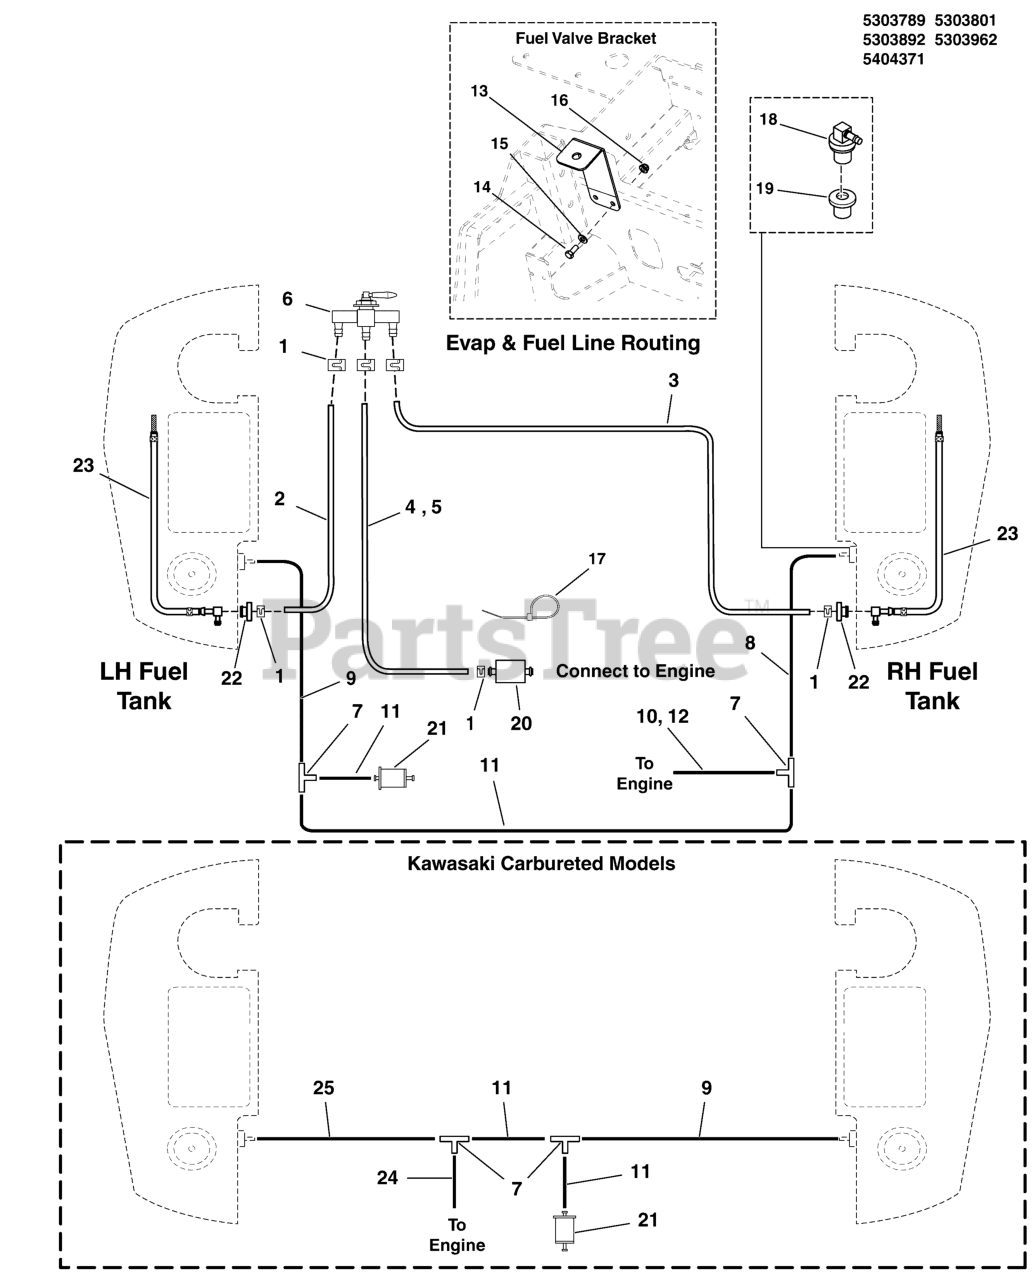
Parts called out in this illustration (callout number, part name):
1	CLAMP, HOSE, EXTERNAL, 1/2 - RED
2	HOSE, 1/4" FUEL, 14.50"
3	HOSE, 1/4" FUEL, 28.50"
4	HOSE, 1/4" FUEL, 10.50"
5	HOSE, 1/4" FUEL, 12.50"
6	VALVE, FUEL SHUT-OFF, 11772
7	FITTING, 3/16" TEE, BARB TYPE, HDPE
8	HOSE, VAPOR, 5MM ID, 18.00 LG
9	HOSE, VAPOR, 5MM ID, 28.50 LG
10	HOSE, VAPOR, 5MM ID, 12.00 LG
11	HOSE, VAPOR, 5MM ID, 3.00 LG
12	HOSE, VAPOR, 5MM ID, 20.00 LG
13	BRACKET, FUEL VALVE, IS2100 - BLK
14	BOLT, 5/16-18 X 3/4 GD5
15	WASHER, 5/16" SAE
16	NUT, 5/16-18 HEX NYLOCK FLANGE
17	TIE, SELF-LOCKING, 12"
18	REMOTE VENT ASSEMBLY
19	GROMMET (SV)
20	FUEL FILTER (SV)
21	FILTER, FUEL
22	BUSHING-FUEL TANK RED RUBBER
23	HOSE ASSEMBLY (SV)
24	HOSE, VAPOR, 5MM ID, 33.00 LG
25	HOSE, VAPOR, 5MM ID, 14.00 LG
